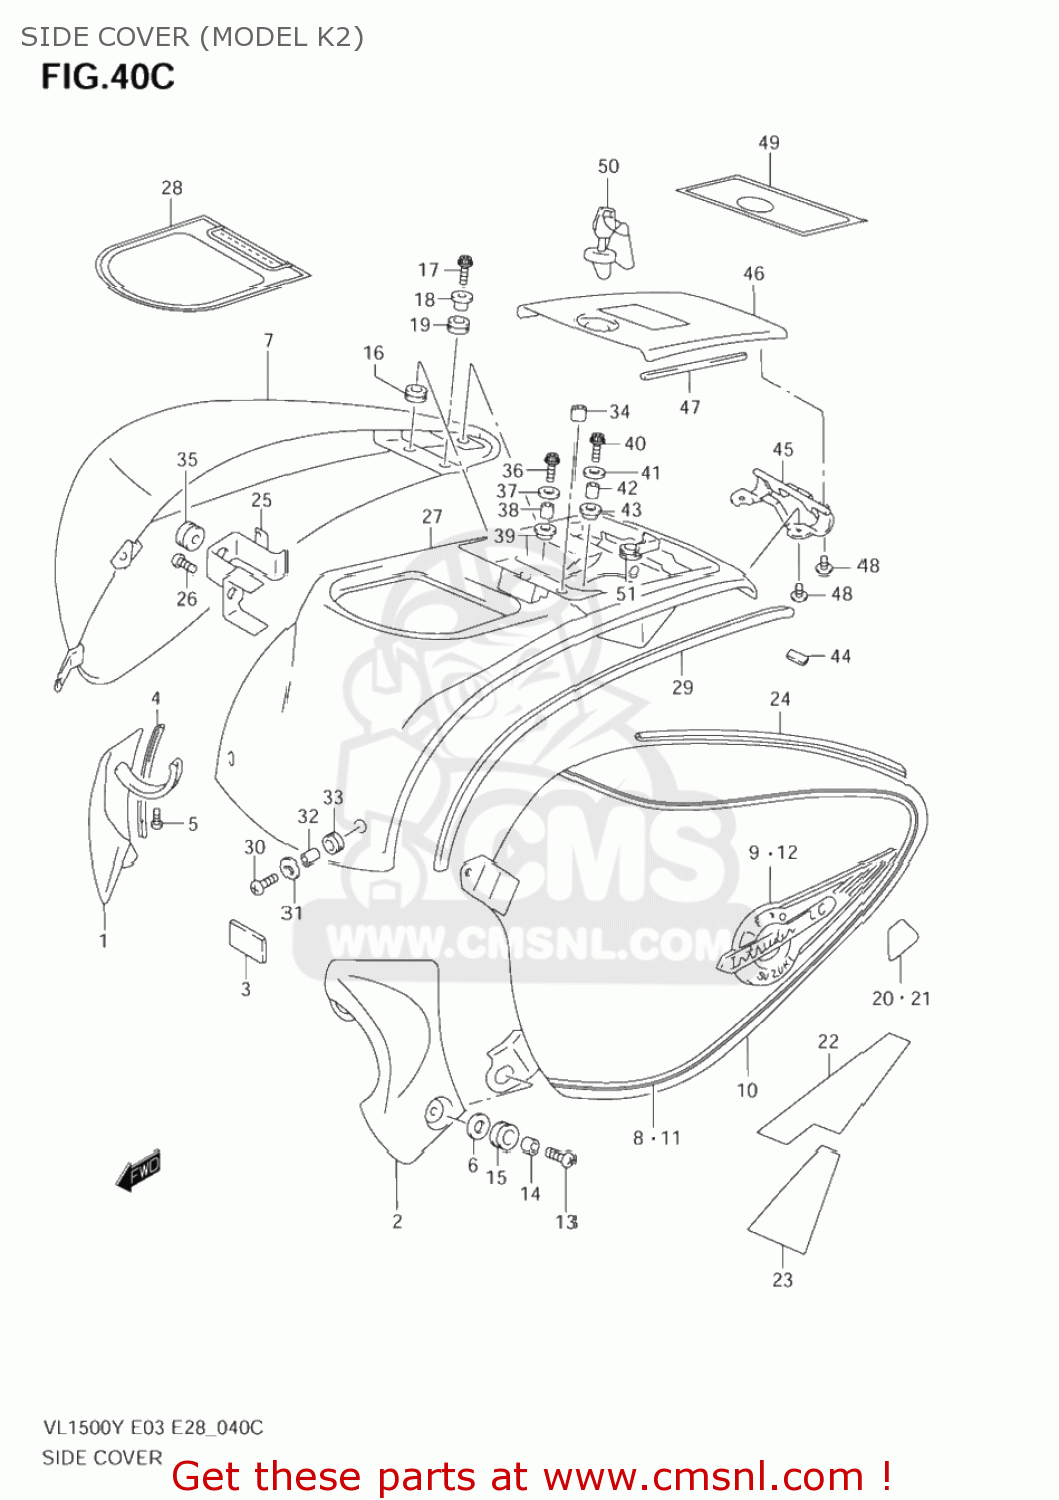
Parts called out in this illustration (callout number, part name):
1	COVER COMP,FRAME HEAD
2	COVER,FRAME HEAD,LEFT
3	CUSHION,METER COVER RE
4	MOLDING,FRAME HEAD COVER
5	SCREW(6X20)
6	WASHER
7	COVER ASSY,SIDE UPR,R
8	TAPE,COVER SIDE UPR,R
9	EMBLEM,TANK COVER,R
10	COVER ASSY,SIDE UPR,L
11	TAPE,COVER SIDE UPR,L
12	EMBLEM,TANK COVER,L
13	SCREW(6X16)
14	SPACER(6.5X9X7.2)
15	CUSHION
16	CUSHION,SIDE UP METER & FRAME
17	BOLT
18	WASHER,SIDE UPR COVER
19	CUSHION,SIDE UPR COVER
20	TAPE,SIDE COVER UPR,R
21	TAPE,SIDE COVER UPR,L
22	CUSHION,SIDE UPR COVER,R
23	CUSHION,SIDE UPR COVER,R
24	MOLDING,SIDE UPPER COVER
25	BRACKET,SIDE UPPER COVER
26	BOLT
27	COVER,METER & FUEL INLET
28	EMBLEM,METER COVER
29	MOLDING,METER COVER
30	SCREW(6X16)
31	WASHER(6.5X18X1.5)
32	SPACER(6.5X9X5.7)
33	CUSHION
34	CUSHION
35	CUSHION
36	BOLT,OIL PAN
37	WASHER(6.5X18X1.6)
38	SPACER(6.5X9X11)
39	CUSHION,METER COVER
40	BOLT MAGNETO S
41	WASHER(6.5X18X1.6)
42	SPACER(6.5X9X5.7)
43	CUSHION
44	CUSHION,METER COVER RE
45	HINGE COMP,FUEL LID
46	LID,FUEL INLET
47	CUSHION,FUEL LID
48	SCREW 6X12
49	EMBLEM,FUEL LID
50	LOCK SET,COVER
51	CUSHION,RR,L
